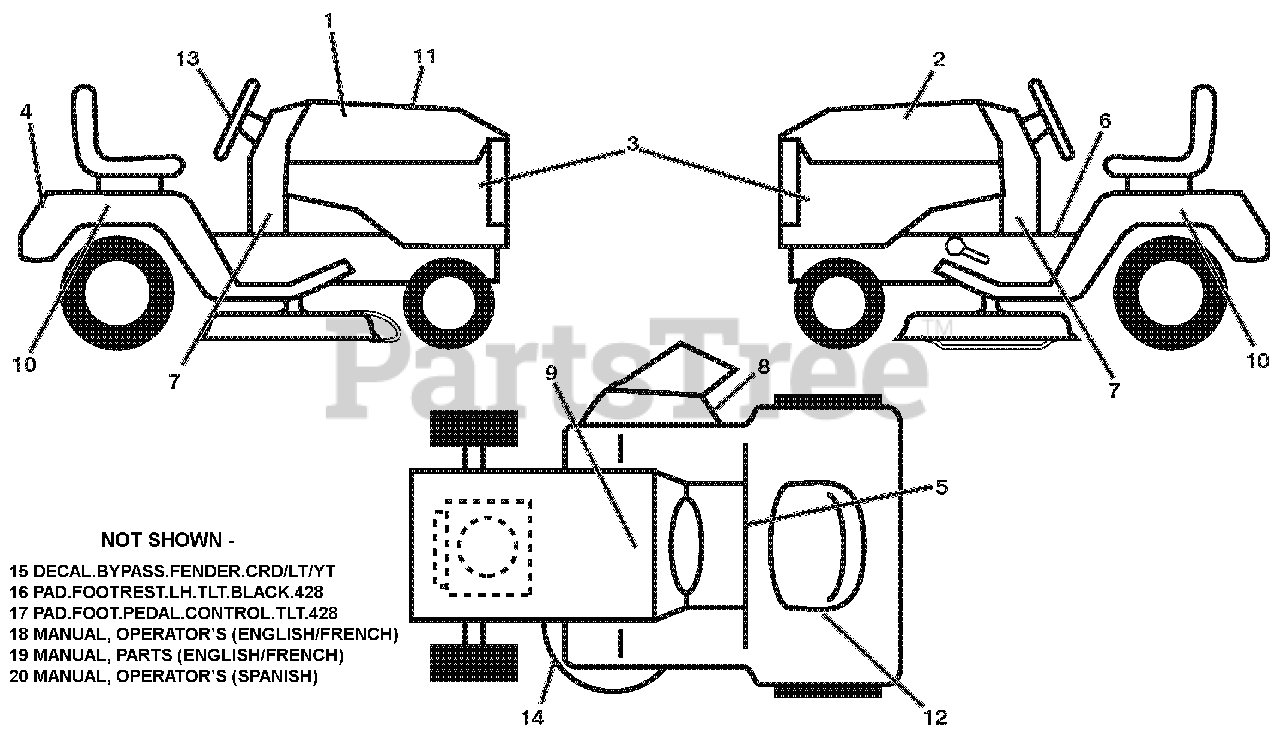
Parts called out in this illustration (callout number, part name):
1	DECAL.HOOD.RH.PRECISION.ARIENS
2	DECAL.HOOD.LH.PRECISION.ARIENS
3	DECAL.SDPNL.PWRDBY KOHL.ARIENS
4	DECAL.FENDER.REAR.ARIENS
5	Decal, Flag
6	DECAL.FENDER.WARNING.ENG/FR.07
7	DECAL.DASH.LWOWER.20HP.ARIENS
8	DECAL.MOWER.WARN.KEEP HAND AWY
9	DECAL.BAT.DAN/POI P/L SYM.WPN
10	DECAL.FENDER.SIDE.HYDRO.ARIENS
11	DECAL.RPL.KH(SNGL).TLW.46.T2ST
12	DECAL, ETHANOL
13	DECAL.WHEEL.STEER.ARIENS
14	DECAL.V-BELT.SCH.42/46"MEC/ELE
15	DECAL.BYPASS.FENDER.CRD/LT/YT
16	PAD.FOOTREST.LH.TLT.BLACK.428
17	PAD.FOOT.PEDAL.CONTROL.TLT.428
18	MANUAL, OPERATOR'S (ENG/FRA)
19	MANUAL, PARTS (ENGLISH/FRENCH)
20	MANUAL, OPERATOR'S (SPANISH)
